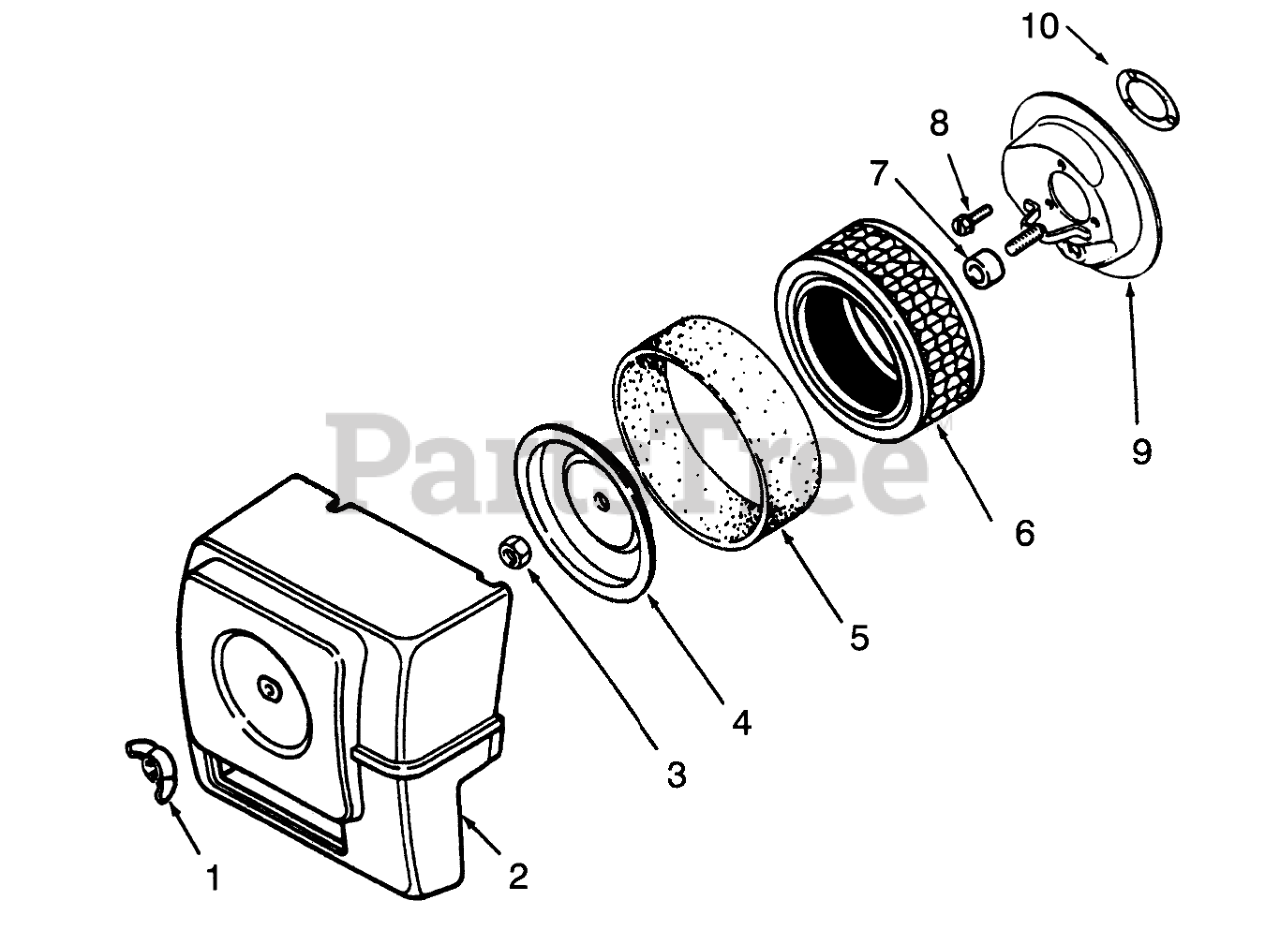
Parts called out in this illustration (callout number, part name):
1	Nut-Wing
2	Cover
4	Air Cleaner Element Cover
5	Element-Precleaner
6	Element
8	Screw
9	Base-AirCleaner
10	Gasket
